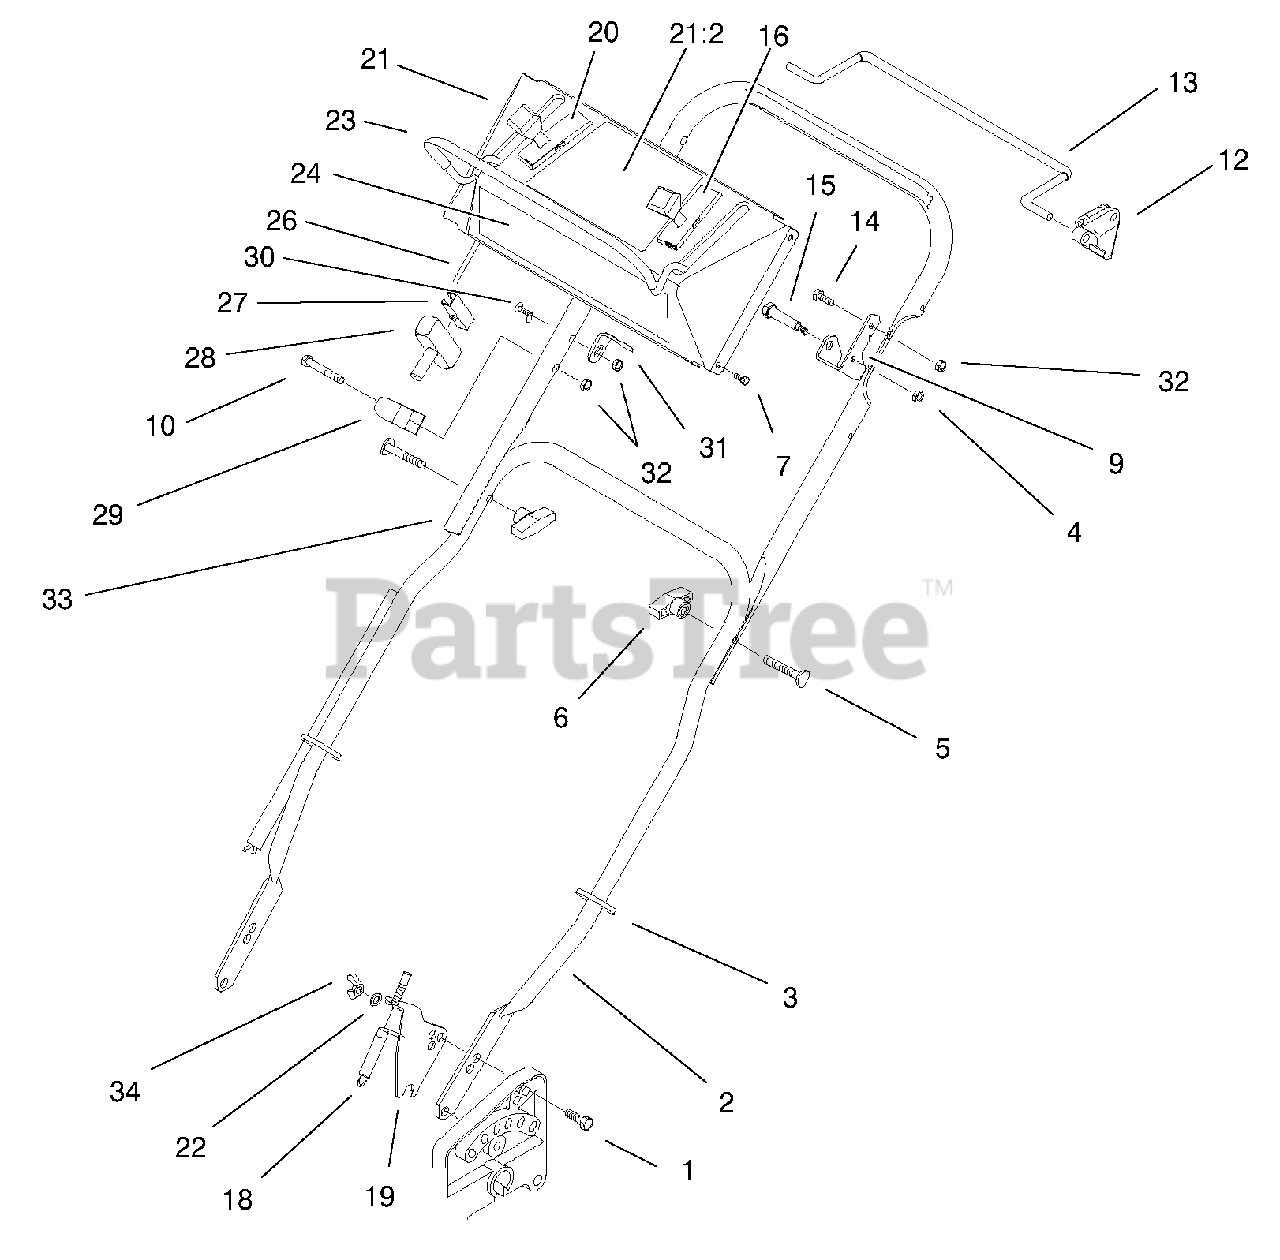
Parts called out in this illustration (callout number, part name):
1	Screw-CARR
2	Handle-Lower
3	Tie Strap
4	Nut-Lock, NI
6	Knob-Handle
9	Bracket-Stop, Bail
10	Screw-HH
12	Stop-Pivot
13	Bail-Control
14	Screw-HH
16	Control ASM-Throttle
18	Cable-Traction
19	Bracket-Traction Cable
20	Cable-Ground Speed
21	Control Panel ASM
21:2	Decal-Control Panel
22	Washer-Lock/Sp
23	Bail-Engine Control
24	Decal-Panel Sp
26	Brake Cable ASM
27	Starter-Clip
28	Handle-Start
29	Rope-Guide
30	Screw-Handle
31	Bracket-Anchor, Cable
32	Nut-Lock, NI
33	Handle-Upper
